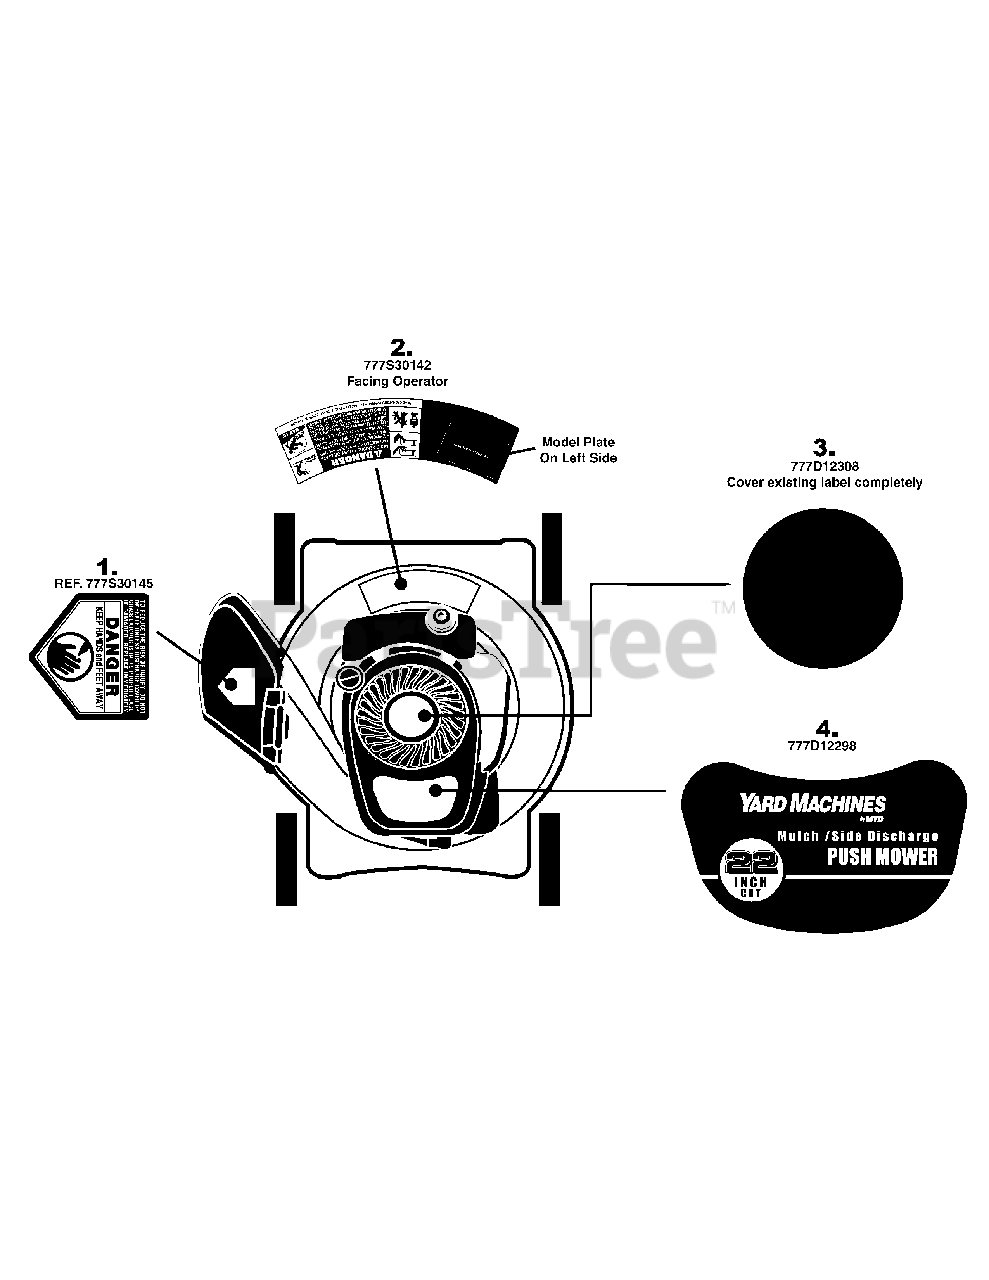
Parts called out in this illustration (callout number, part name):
1	LABEL
2	LABEL-DANGER CURVE
3	LABEL-MOWER SHROUD TEC/SPIN
4	LABEL-MOWER SHROUD YARD MACHINE
